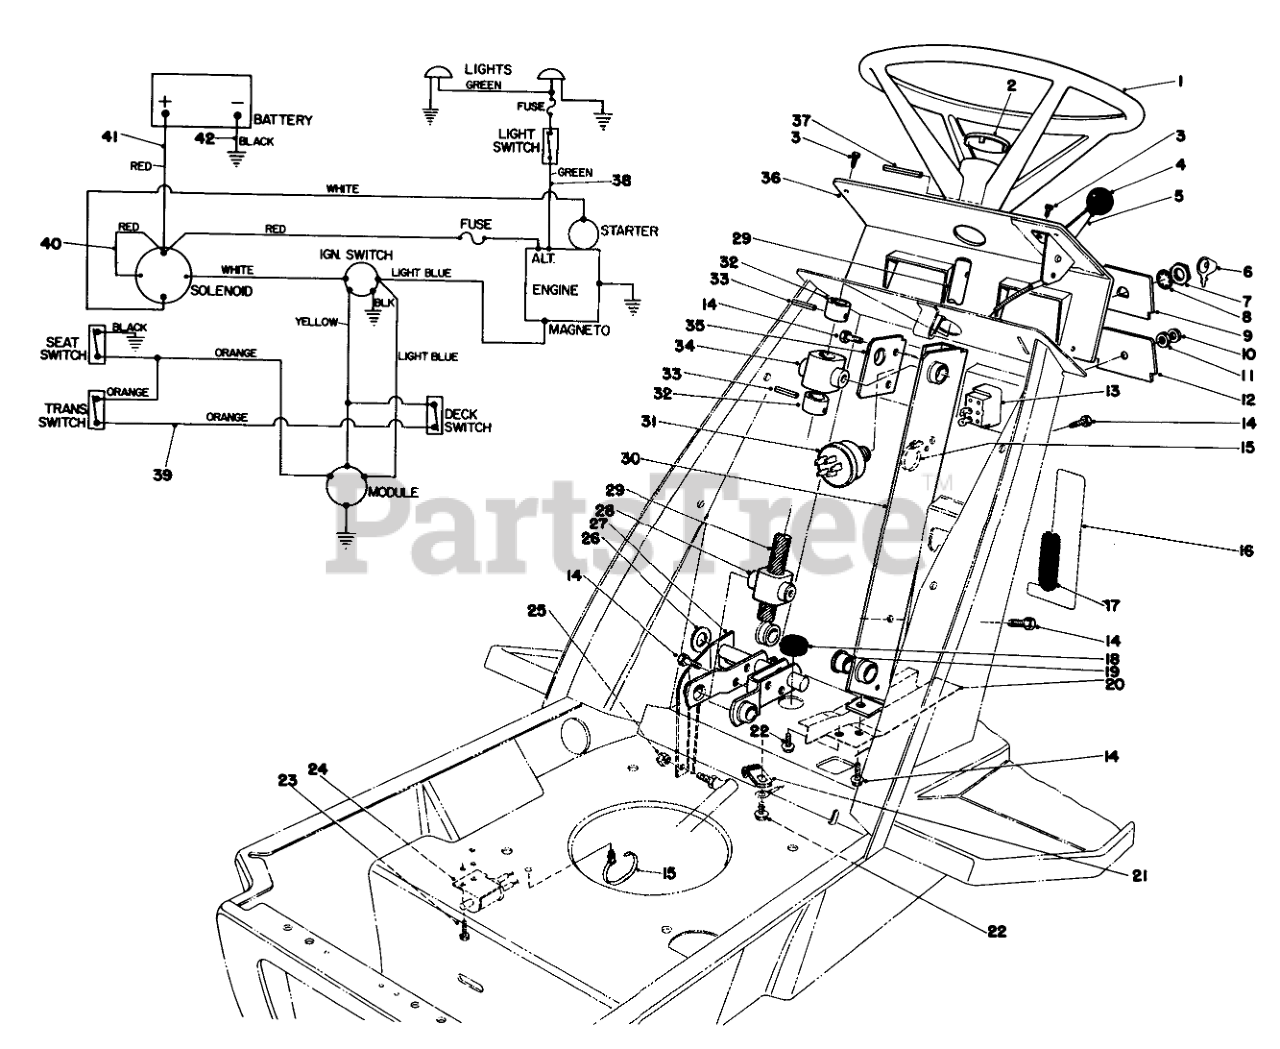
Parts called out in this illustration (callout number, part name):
1	Steering Wheel
2	Cap Steering Wheel
3	SCREW-HWHTF
4	KNOB-CONTROL
5	Throttle Control (Incl. Ref. #4)
6	Key
8	WASHER-TOOTH, INTERNAL
9	DASH PANEL INSERT
10	NUT-BULB
11	Locknut
12	DASH PANEL INSERT
13	Light Switch ( Model #57385) (Incl. Ref. #10 & 11)
14	SCREW-HWHTF
15	TIE-MOUNT, PUSH
16	Decal-Deck
17	EDGE MOULDING
18	GROMMET
19	BEARING-FLANGE
20	WIRE HARNESS SHLD B
21	CLIP-FUEL LINE
22	SCREW-HWH
23	SCREW-TAPTITE
24	DECK INTERLOCK SWITCH
25	Nut
26	WASHER
27	STEERING LINK WA BO
28	FOLLOWER STEER SHAFT
29	STEERING SHAFT
30	STRG BRKT B
31	Ignition Switch (Incl. Ref. #6-8)
32	STRG SHAFT COLLAR
33	PIN-SPRING
34	BRG STEERING SHAFT
35	STRG BRG SUPPORT
36	DASH PANEL
37	PIN-ROLL
38	WIRE HARNESS
39	Wire Harness
40	SOLENOID WIRE
41	WIRE ASM
42	WIRE ASM
